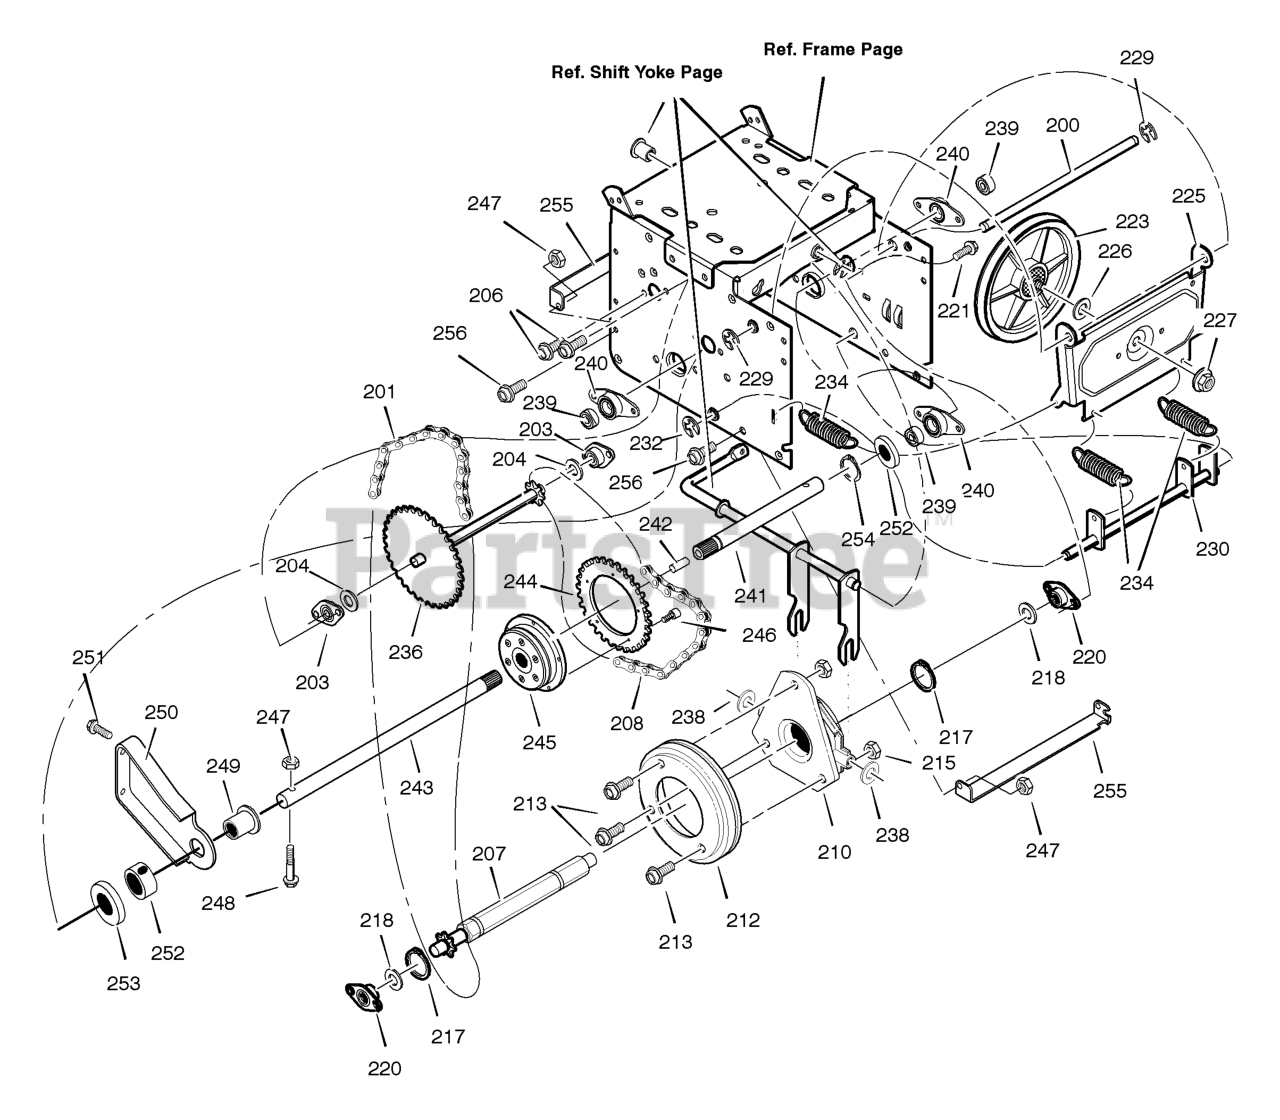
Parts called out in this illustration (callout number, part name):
200	LF AXLE, SWING PLATE YZ
201	CHAIN, ROLLER #420x19.00
203	BEARING AND RETAINER, ASSY
206	SCREW, TAP 5/16-18 x 0.5
207	ASSY, HEX SHAFT
208	CHAIN, ROLLER #420x18.00 LG
210	BEARING, TRUNION CLUTCH R
212	WHEEL, FRICTION DISC
215	NUT, KEPS HEX 1/4-20
217	RING, RETEXT
220	BEARING AND RETAINER, ASSY
221	SCREW, TAP 5/16-18 x .5
223	FRICTION PULLEY
225	LF PLATE, SWINGING YZ
226	SPACER, FRICTION PULLEY
227	NUT, FLANGE LOCK 3/8-24
229	RETAINER, RING
230	ASSEMBLY, SPRING LINK STEERABLE
232	RETAINER, RING
234	SPRING, EXTENSION
236	SPROCKET SET 33T/7
238	WASHER, FLAT
239	BEARING, BALL
240	RETAINER, BEARING
241	AXLE, LEFT
242	PIN, AXLE
243	AXLE AND BUSHING, RIGHT
244	SPROCKET
245	CLUTCH, AUTO LOCK
247	NUT
248	BOLT
249	BEARING, AXLE
250	BRACKET, AXLE SUPPORT
251	SCREW
252	COLLAR, LOCKING
254	RETAINER, RING
255	BRACKET, SUPPORT
